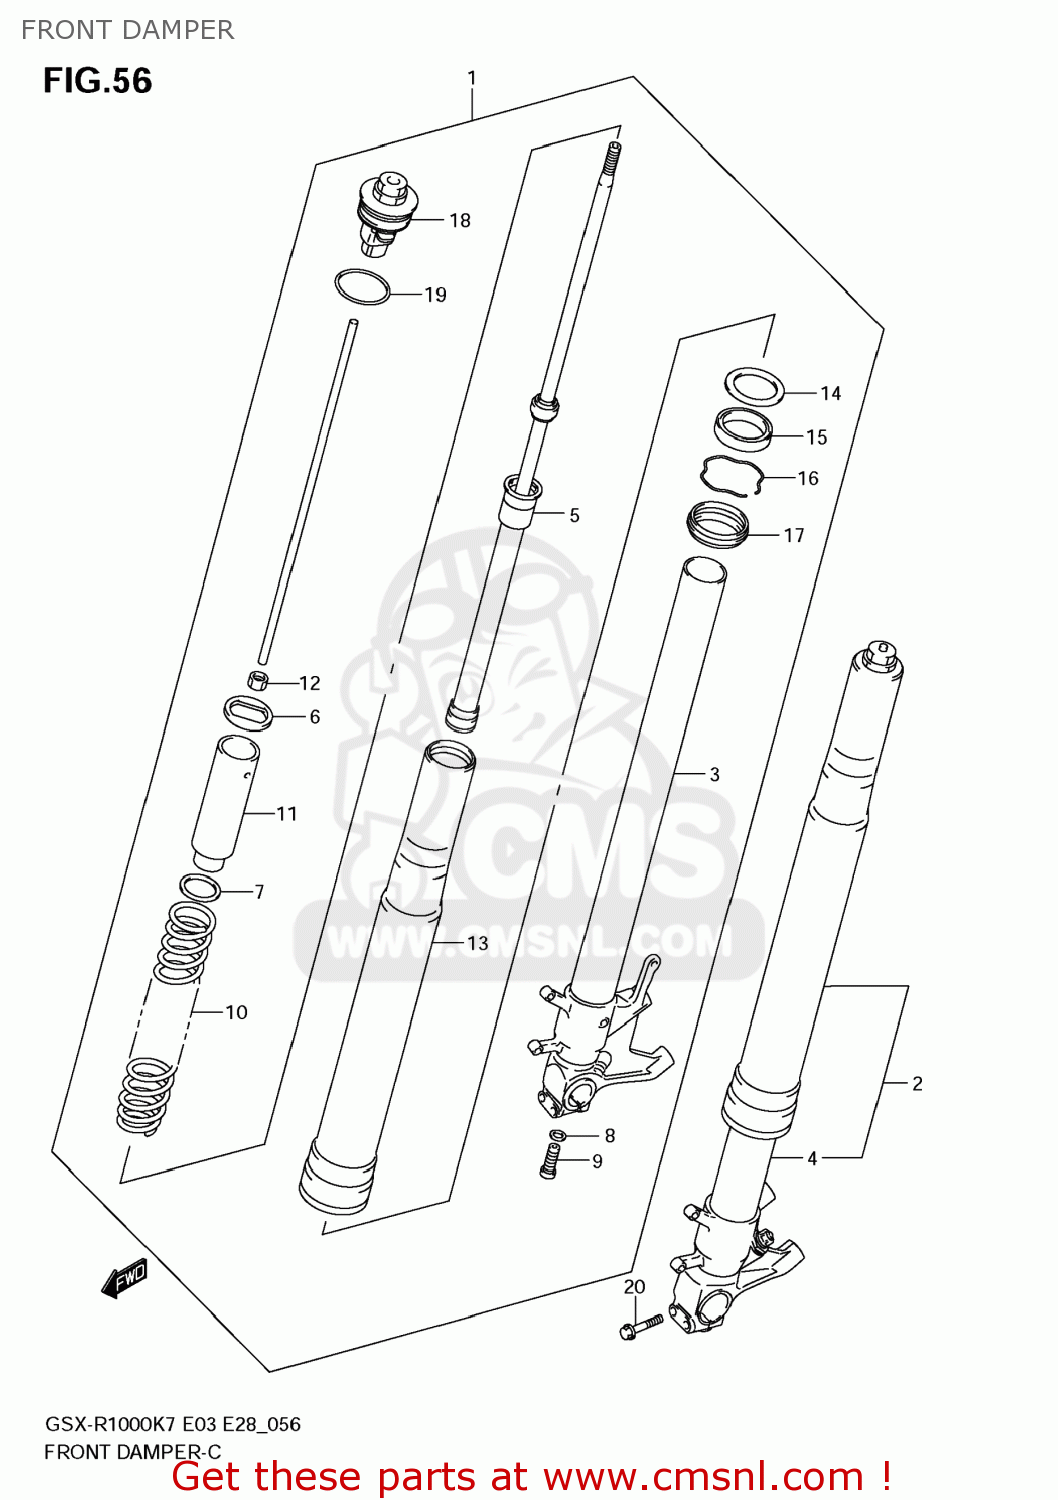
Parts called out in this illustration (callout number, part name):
1	DAMPER ASSY,FR FORK,R
2	DAMPER ASSY,FR FORK,L
3	TUBE,INNER,R
4	TUBE,INNER,L
5	CYLINDER
6	GUIDE,SPRING
7	WASHER
8	GASKET (NAS)
9	BOLT
10	SPRING,FR
11	SPACER,SPRING
12	NUT
13	TUBE,OUTER
14	WASHER
15	SEAL,OIL
16	RING,STOPPER
17	SEAL,DUST
18	CAP
19	O RING
20	BOLT
